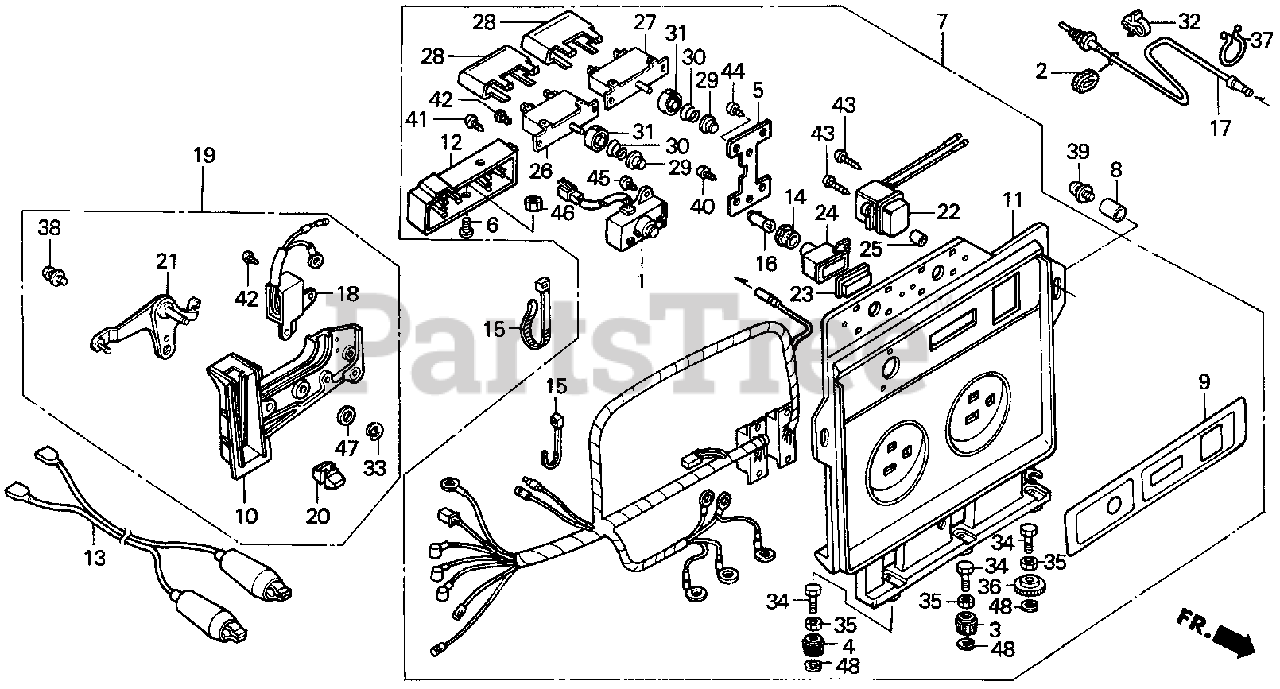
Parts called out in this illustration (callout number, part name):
1	ALERT UNIT, OIL
3	CLAMP, TERMINAL (B)
4	CLAMP, TERMINAL (A)
5	HOLDER, CONNECTOR
6	SCREW, ELECTRIC (4X6)
7	PANEL ASSY., CONTROL
8	COLLAR, PANEL
9	MARK, PANEL
9	MARK, PANEL (E)
10	BRACKET, ENGINE SWITCH
11	PLATE, BASE
13	WIRE ASSY., CHARGE
14	GROMMET
15	BAND
16	BULB, DASH (6V 3W)
18	SWITCH ASSY., STOP
19	BRACKET ASSY., ENGINE SWITCH
20	KNOB, ENGINE SWITCH
21	LEVER, PETCOCK
22	METER, FREQUENCY
23	LENS, LAMP
24	CASE, LAMP
25	COLLAR
26	PROTECTOR, D.C. CIRCUIT (12A)
27	PROTECTOR, CIRCUIT (8A)
28	COVER, CIRCUIT PROTECTOR
29	CAP, BREAKER
30	SPRING, RETURN
31	HOLDER, BREAKER
33	CLIP, LOCK PIN
34	BOLT, TERMINAL (6X25)
35	NUT, CLAMP (6MM)
36	NUT, SPECIAL (6MM)
38	SCREW-WASHER (5X16)
39	SCREW-WASHER (5X12)
40	SCREW, TAPPING (4X10)
41	SCREW, TAPPING (4X20)
42	SCREW, TAPPING (3X8)
43	SCREW, TAPPING (3X16)
44	SCREW, TAPPING (3X8)
45	SCREW, TAPPING (4X16)
46	NUT, HEX. (4MM)
47	WASHER, PLAIN (6MM)
48	E-RING (3MM)
